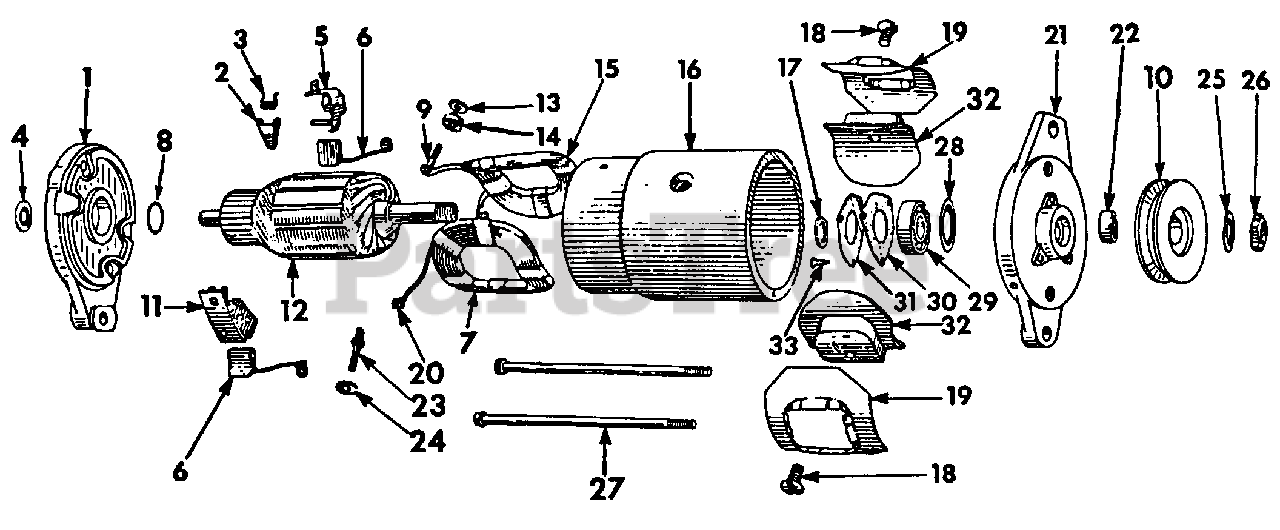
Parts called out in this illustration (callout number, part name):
1	Frame Assy, Commutator End
3	Spring, Brush
4	Plug, Commutator End Wick
5	Holder, Brush Ground
6	Brush
7	Coil, Field
8	Retainer, Commutator End
9	Stud, Terminal Field
10	Pulley, Motor Generator
11	Holder, Brush Insulated
12	Armature
13	Washer, Terminal Stud Insulating
14	Bushing, Field Terminal Insulating Inside
15	Coil, Field
16	Frame
17	Collar, Drive End Spacer, Inside
18	Screw, Pole Shoe
19	Insulator, Field Coil
20	Clip, Terminal to Brush
21	Frame, Drive End
22	Collar, Drive End Space
23	Stud, Terminal Armature
24	Bushing, Armature Terminal Insulating
25	Washer, Drive End Shaft Nut Lock
26	Nut, Drive End Shaft
27	Bolt, Thru
28	Plate, Drive End Grease Slinger
29	Ball Bearing, Drive End
30	Gasket, Drive End Retainer Plate
31	Plate, Drive End Retainer
32	Shoe, Pole w/Notch
33	Screw, Drive End Retainer Plate
